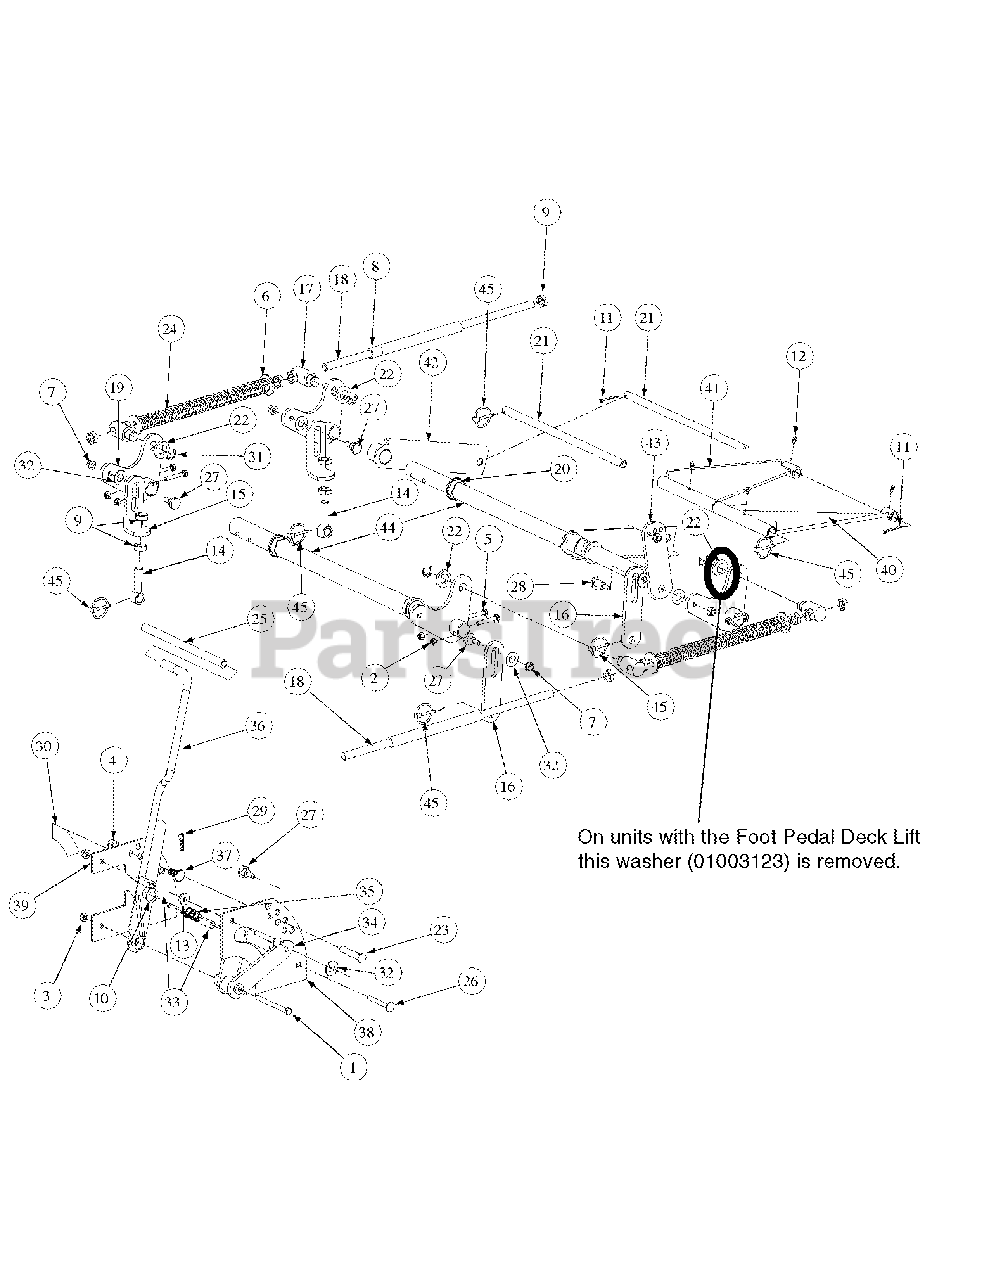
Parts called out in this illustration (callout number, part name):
1	Hex Cap Screw, 3/8-16, 3.75
2	Nut, 5/16-18, Nylock
3	Nylock Insert Lock Nut, 3/8-16
4	Nylock Insert Lock Nut, 1/2-13
5	Socket Head Capscrew, 5/16-18 x 2
6	Flat Washer, 5/8
7	Hex Nut, Flange Lock, 3/8-16
8	PVC Hose, 5/8 ID x 13/16 OD x 8"
9	Jam Nut, 5/8-11
10	Flat Washer, .06, .776, 1.25
11	Cotter Pin, 3/16 x 1-1
12	Grease Fitting, 1/4-28 x 3/16
13	Idler Washer
14	Eye Bolt, 5/8ID
15	Eye Bolt Mount Link, 5/8 ID
16	Deck Link
17	Ferule Lift
18	Lift Connector Rod
19	Bellecrank Weldment Lift
20	Hex Flange Bearing, 1.25 ID
21	Front Lift Link, Rod Mount
22	Spacer, .812 ID x .218 Lg.
23	Clevis Pin, .500 Dia. x 2.625 Lg.
24	Lift Compression Spring
25	Lift Handle Grip
26	Carriage Bolt, 3/8-16, 2.75
27	Shoulder Screw, 0.625 OD x .437 Lg.
28	Shoulder Screw, 0.625 OD x .830 Lg.
29	Cotter Pin, .148 x 3.00
30	Decal Height Indicator
31	E Clip, 3/4 Dia.
32	Nylon Flat Washer, 5/8
33	Spacer, .39 ID x .63 OD x 1.442
34	Lift Pivot Assembly
35	Lift Handle Spring
36	Lift Handle Assembly
37	Shoulder Screw, 5/8 OD x 0.264
38	Outer Lift Index Plate
39	Inner Lift Index Plate
40	Bearing Lift Brace Assembly, Right Hand
41	Bearing Lift Brace Assembly, Left Hand
42	Front Frame Strut Assembly
43	Lift Link Adjustment
44	Lift Shaft Holder
45	Linch Pin, 3/16
